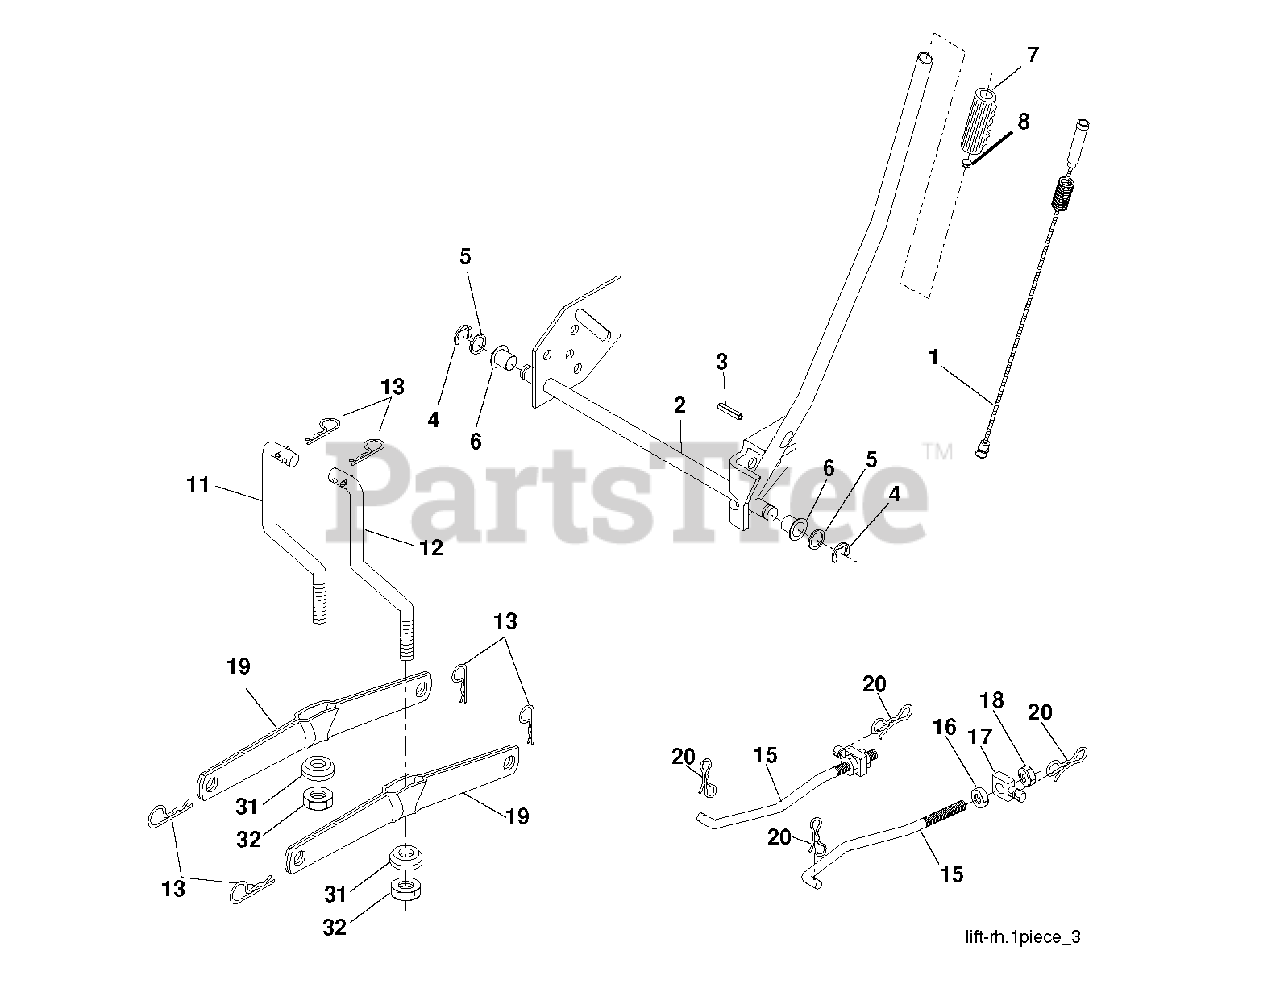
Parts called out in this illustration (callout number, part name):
1	PLUNGER.ASM.LIFT.LVR.BLK.17.32
2	SHAFT ASM R HANDLE
4	RETAINING RING LT
6	BEARING.NYLON
7	GRIP
11	LINK LIFT LH
12	LINK LIFT RH
13	RETAINER-SPRNG RB
15	LINK.SUSPENSION.FRONT
16	NUT
18	NUT
19	ARM.REAR.SUSPENSION
20	PIN.COTTER.7/16.BOW TI
31	BEARING.PIVOT.LIFT
32	NUT CROWNLOCK 3/8-24
